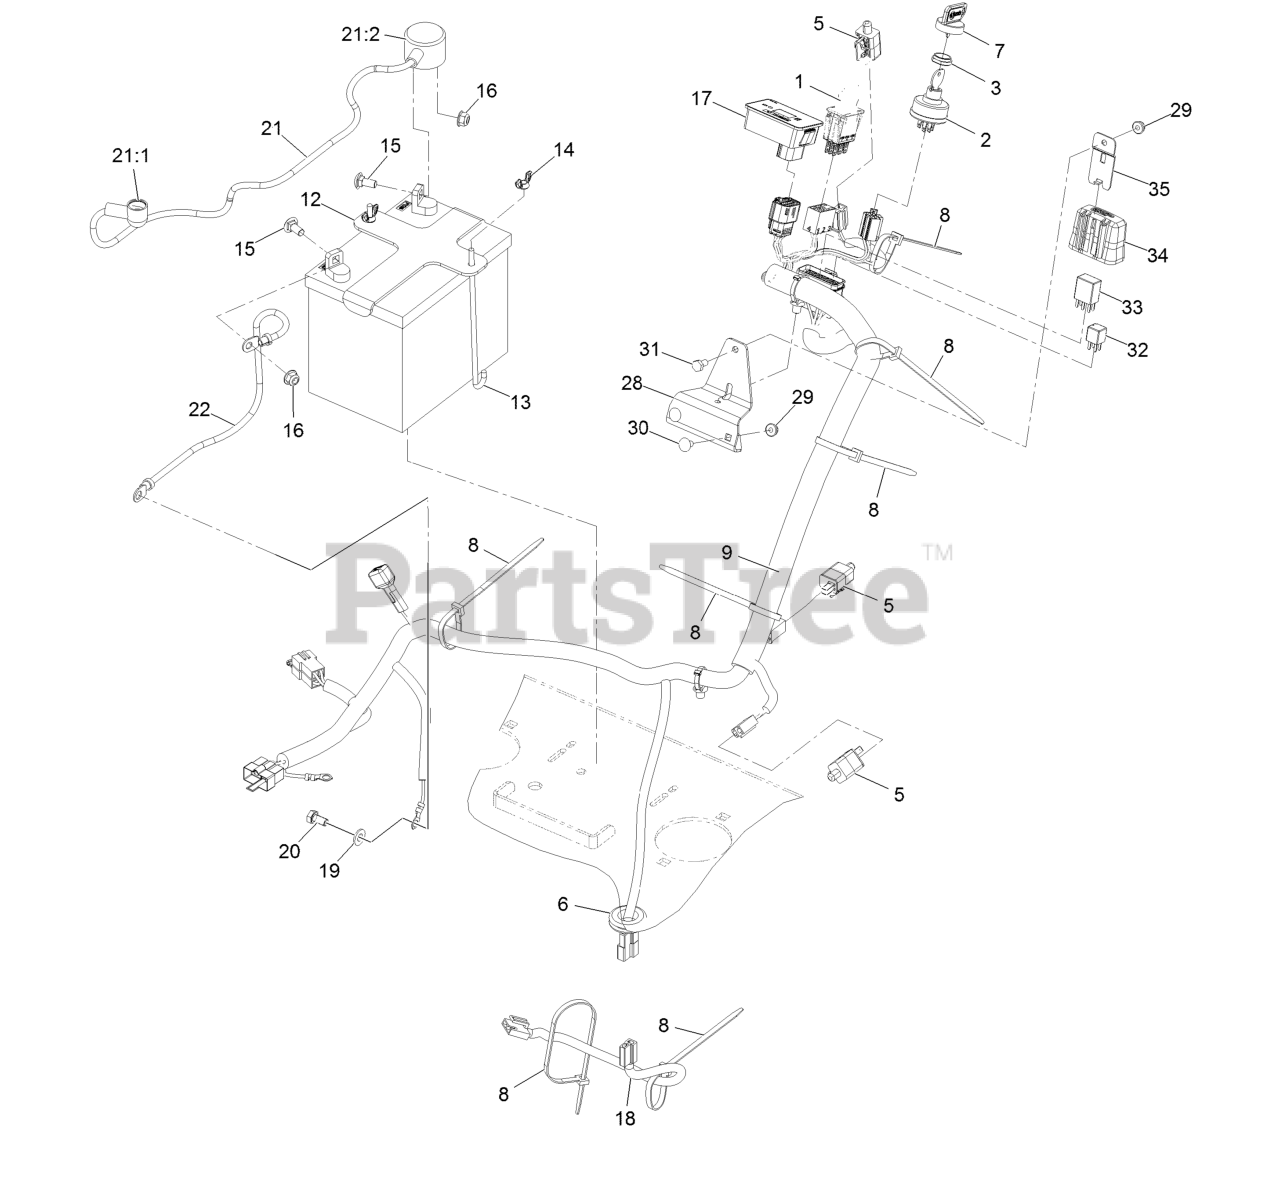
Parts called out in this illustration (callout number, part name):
1	Switch-PTO
2	Switch, Key Start
3	Nut-Ignition
6	Grommet
7	Key-Exmark Logo
8	Tie-Cable 7 15/16 (Large)
9	Harness-Wiring
12	Bracket, Battery Hold Down
13	Bolt-Holddown
14	Wingnut-Nyloc 1/4-20
15	Bolt-Carriage 5/16-18 X 3/4
16	Nut-Nyloc 5/16-18 Flg
17	Module-Hour Meter
18	Harness-Clutch Pigtail
20	Screw-HH M8-1.25 X 16Mm
21	Positive Battery Cable ASM
21:1	Insulator-Solenoid
21:2	Insulator-Battery
22	Cable-Battery, Negative
28	Bracket, Mounting Pdm
29	Nut-Nyloc 1/4-20 Flg
30	Bolt-Carriage 1/4-20 X 1/2
31	Screw-HH 1/4-20 X 1/2
32	Relay-Micro
33	Relay-Micro 280, Spdt
34	Cover-Block, Fuse
35	Clip-Mounting
